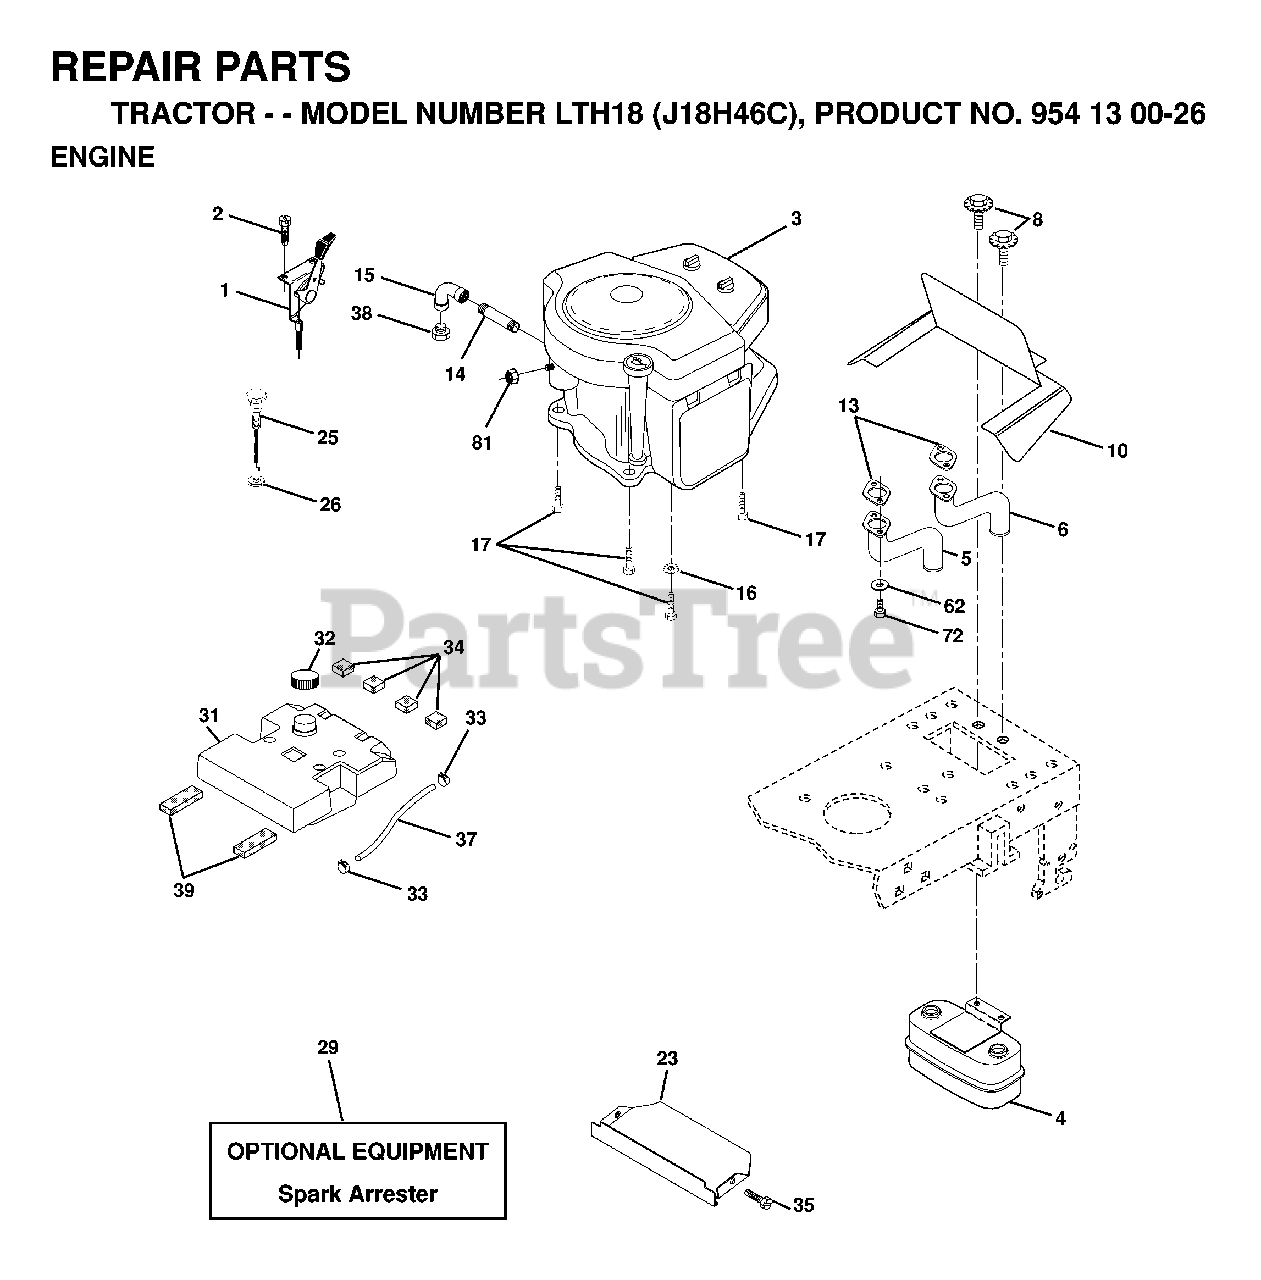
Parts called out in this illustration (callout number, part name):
1	CONTROL THROTTLE 36"
2	SCREW LT
4	MUFFLER.TWIN.CYL.LOW.TONE
5	TUBE MANIFOLD LH
6	EXHAUST TUBE RH
8	BOLT HEX WASHER HD 5/16-18
10	SHIELD.BROWNING.B&S
13	GASKET.MUFFLER
14	PIPE NIPPLE LT
15	ELBOW
16	LOCKWASHER
17	SCREW LT
23	PROTECTOR
25	CONTROL, CHOKE
26	NUT KEPS 3/8 - 24 UNF
29	ARRESTER SPARK (OPTIONAL)
31	TANK.FUEL(3.5.GAL)
32	FUEL CAP
33	HOSE CLAMP
34	PAD-SPACER LT
35	SCREW
39	PAD IDLER TI
62	LOCKWASHER
72	SCREW
81	NUT FLANGE 1/4-20 STARTER NUT
